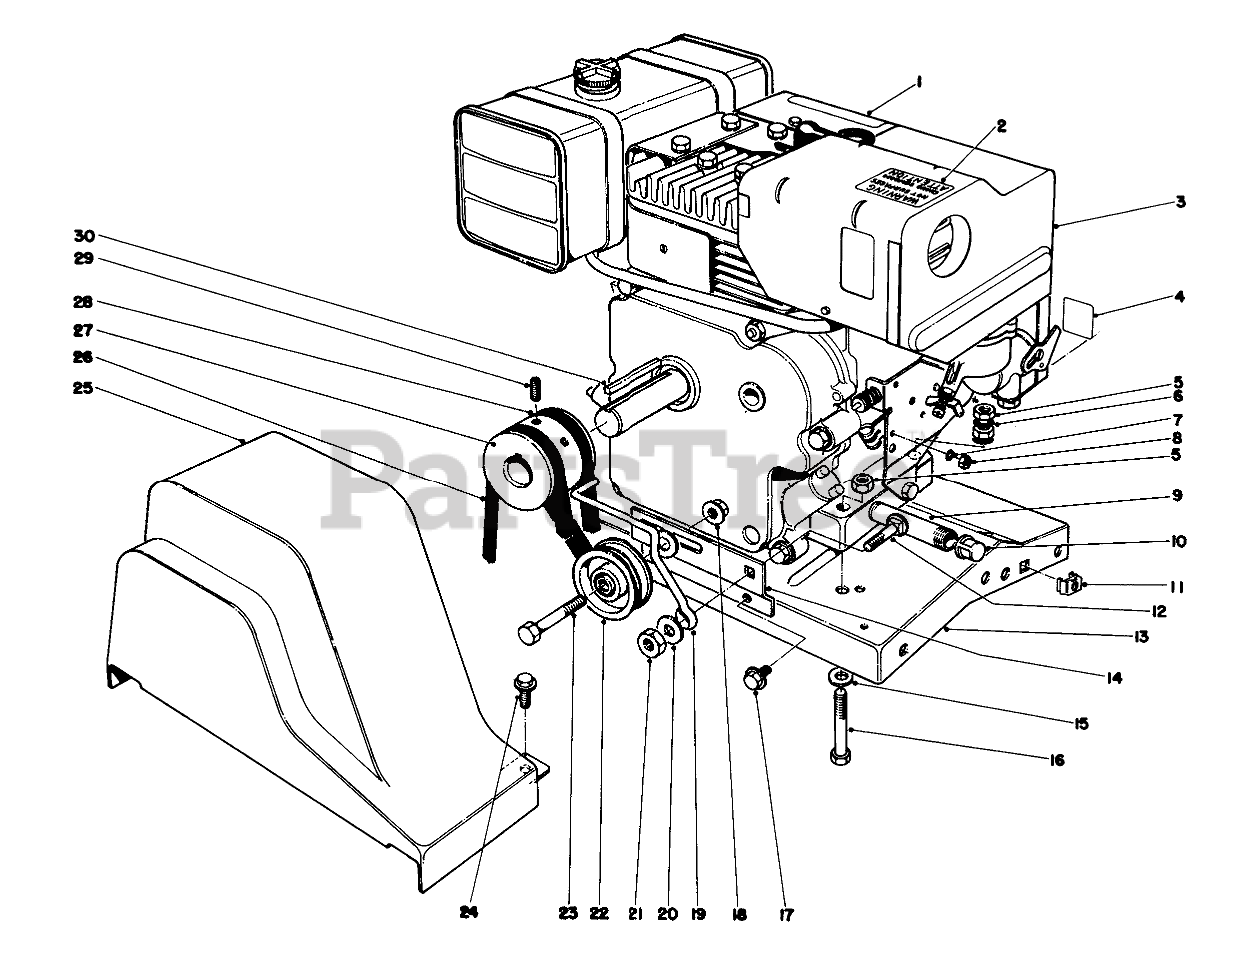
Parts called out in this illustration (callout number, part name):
1	HAZARDS CAUTION DECAL
2	Decal
3	Engine
4	Decal-Choke
5	NUT-LOCK, NI
6	Lockwasher
7	WASHER-LOCK/INT
8	NUT-LOCK
9	NIPPLE-PIPE
10	CAP-PIPE
11	Retained Nut
12	SCREW-CARR
13	Base-Engine
14	Belt Idler Bracket
15	WASHER-PLAIN
16	SCREW-HH
17	SCREW-HHFTF
18	NUT-HHF, WHIZ
19	BELT GUIDE
20	WASHER-FLAT
21	NUT-HEX
22	PULLEY B
23	SCREW-HH
24	SCREW-HWH
25	BELT GUARD
26	V-BELT
27	ENGINE PULLEY
28	V-BELT
29	Screw-Set
